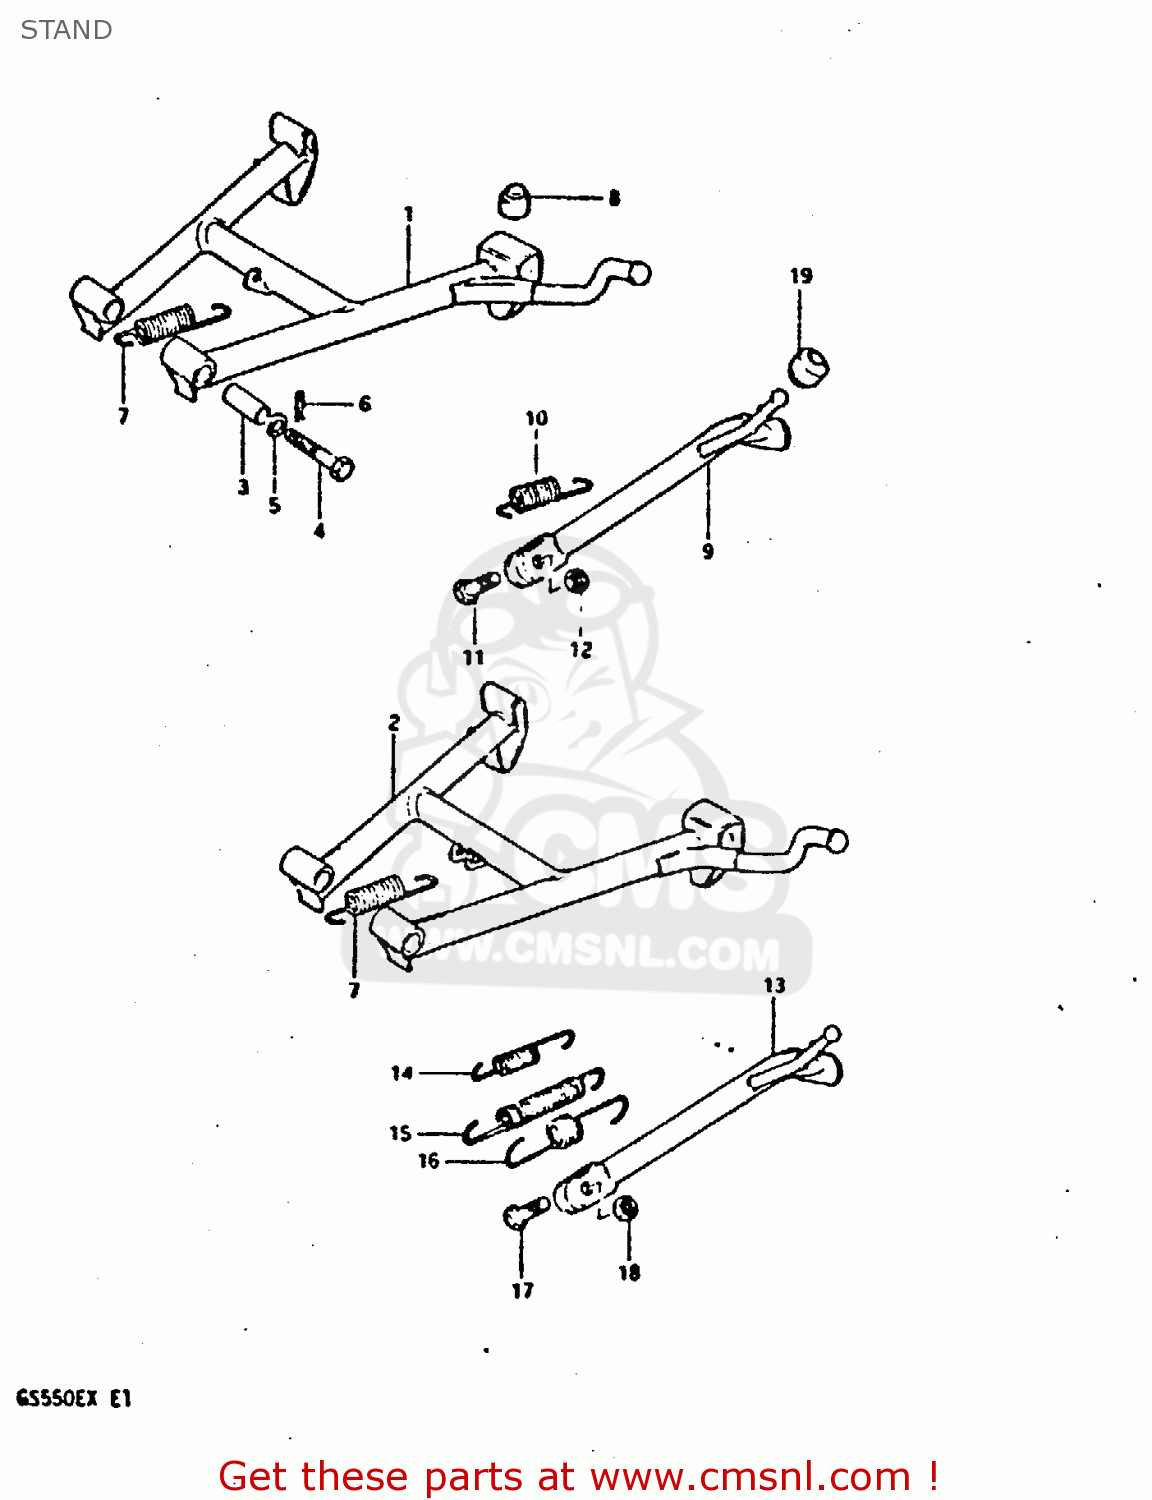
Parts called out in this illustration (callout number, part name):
1	STAND,CENTER
3	SPACER(10X16X38.8)
4	BOLT
5	LOCK WASHER
6	CLIP
7	SPRING
8	CUSHION
9	STAND,SIDE
10	SPRING
11	BOLT(10X30)
12	NUT
19	CUSHION
